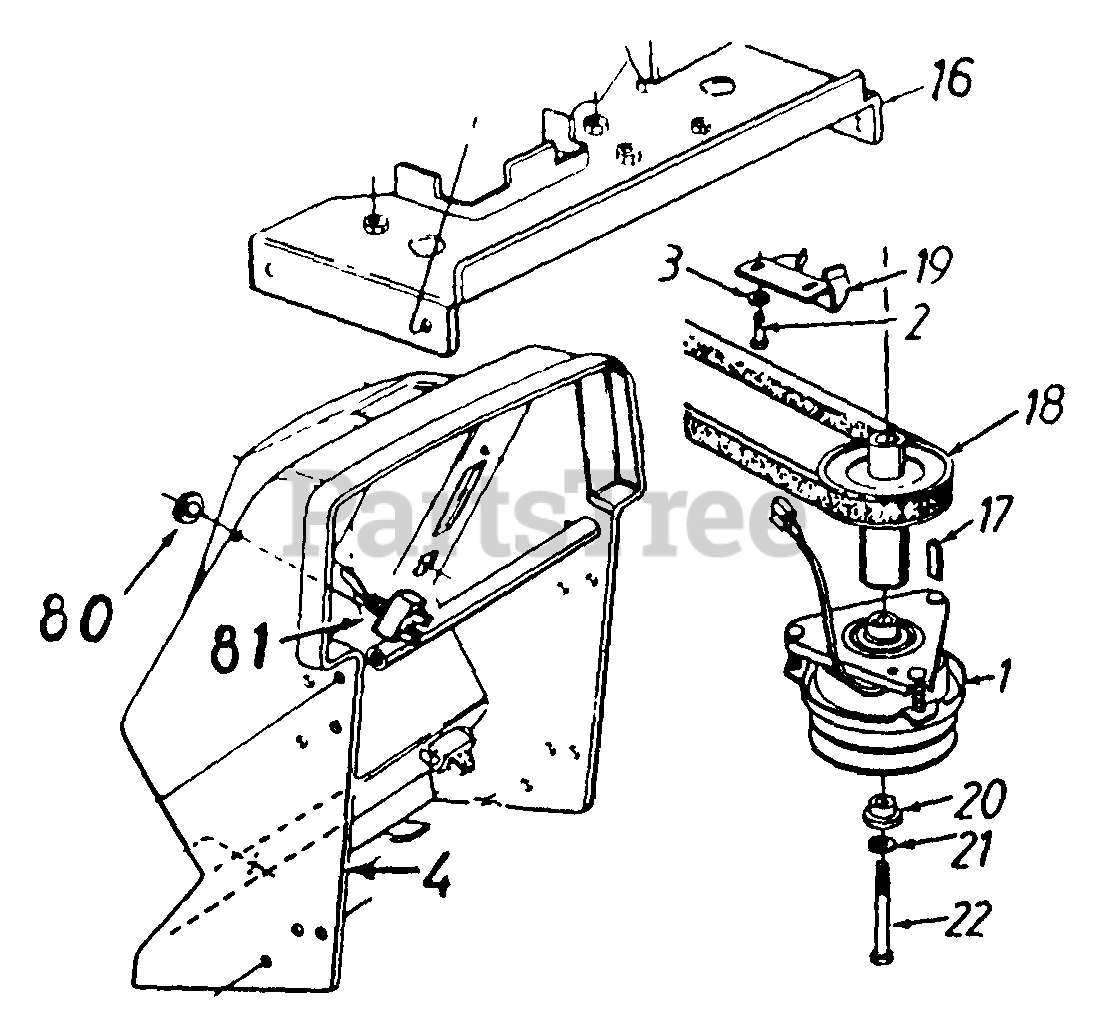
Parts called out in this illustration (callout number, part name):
1	Electric Clutch
2	Hex Bolt 5/16-18 x .75" Lg. (Gr. 5)
3	Bell-Wash. .345" I.D. x .88"
16	Belt Guard Brkt. Ass'y
17	Sq. Key 1/4" x 1 5" Lg.
18	Engine Pulley
21	L-Wash. 7/16" I D.
22	Hex Bolt 7/16-20 x 3 25" Lg. (Gr 5)
80	Hex Nut 1/2-27 Thd
81	PTO Switch
